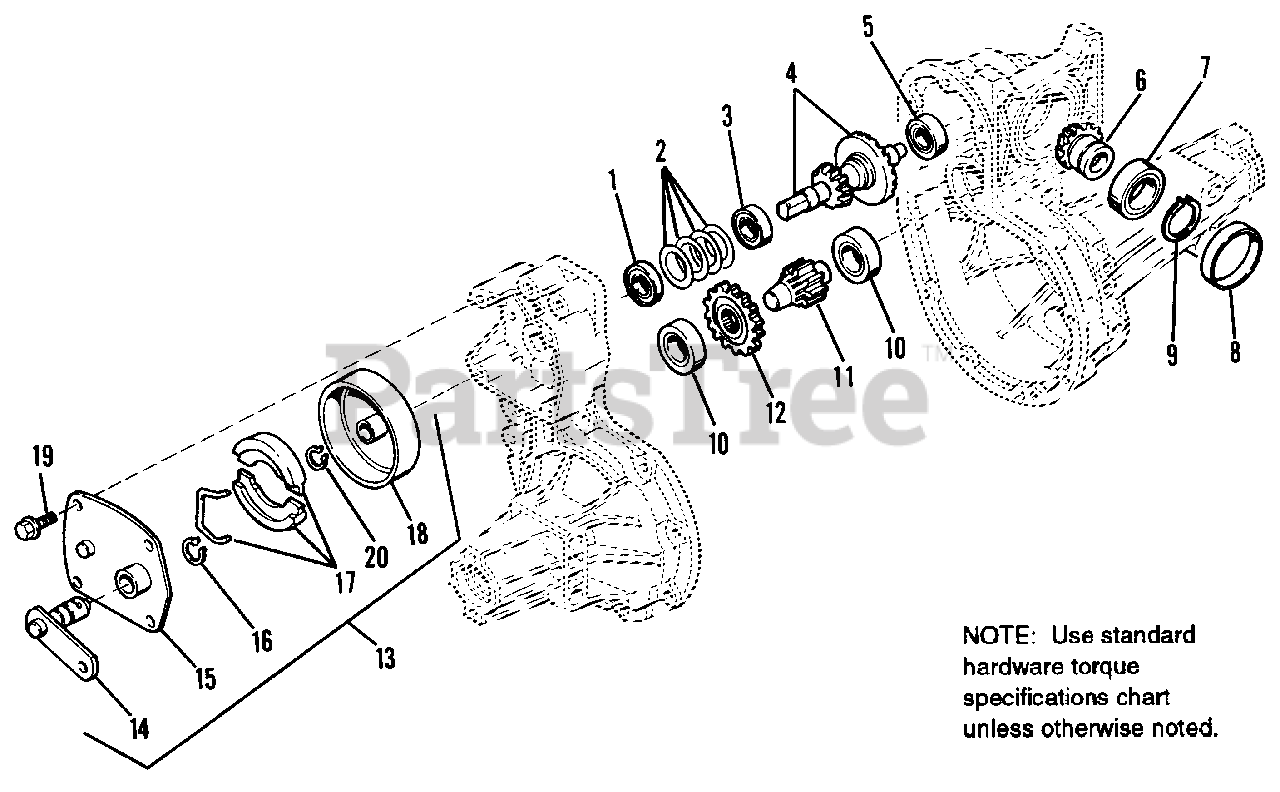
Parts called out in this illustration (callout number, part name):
4	REDUCTION SHAFT ASSY.
6	MOTOR GEAR, Spiral, 19 Tooth
11	SHAFT, Final Pinion
12	GEAR, Final Shaft, 24 Tooth
13	BRAKE ASSY. (Includes Ref. Nos. 14 thru 18)
14	SHAFT, Cam Lever
15	COVER, Brake
17	SHOE SET, Brake
18	DRUM, Brake
19	BOLT, w/Washer
